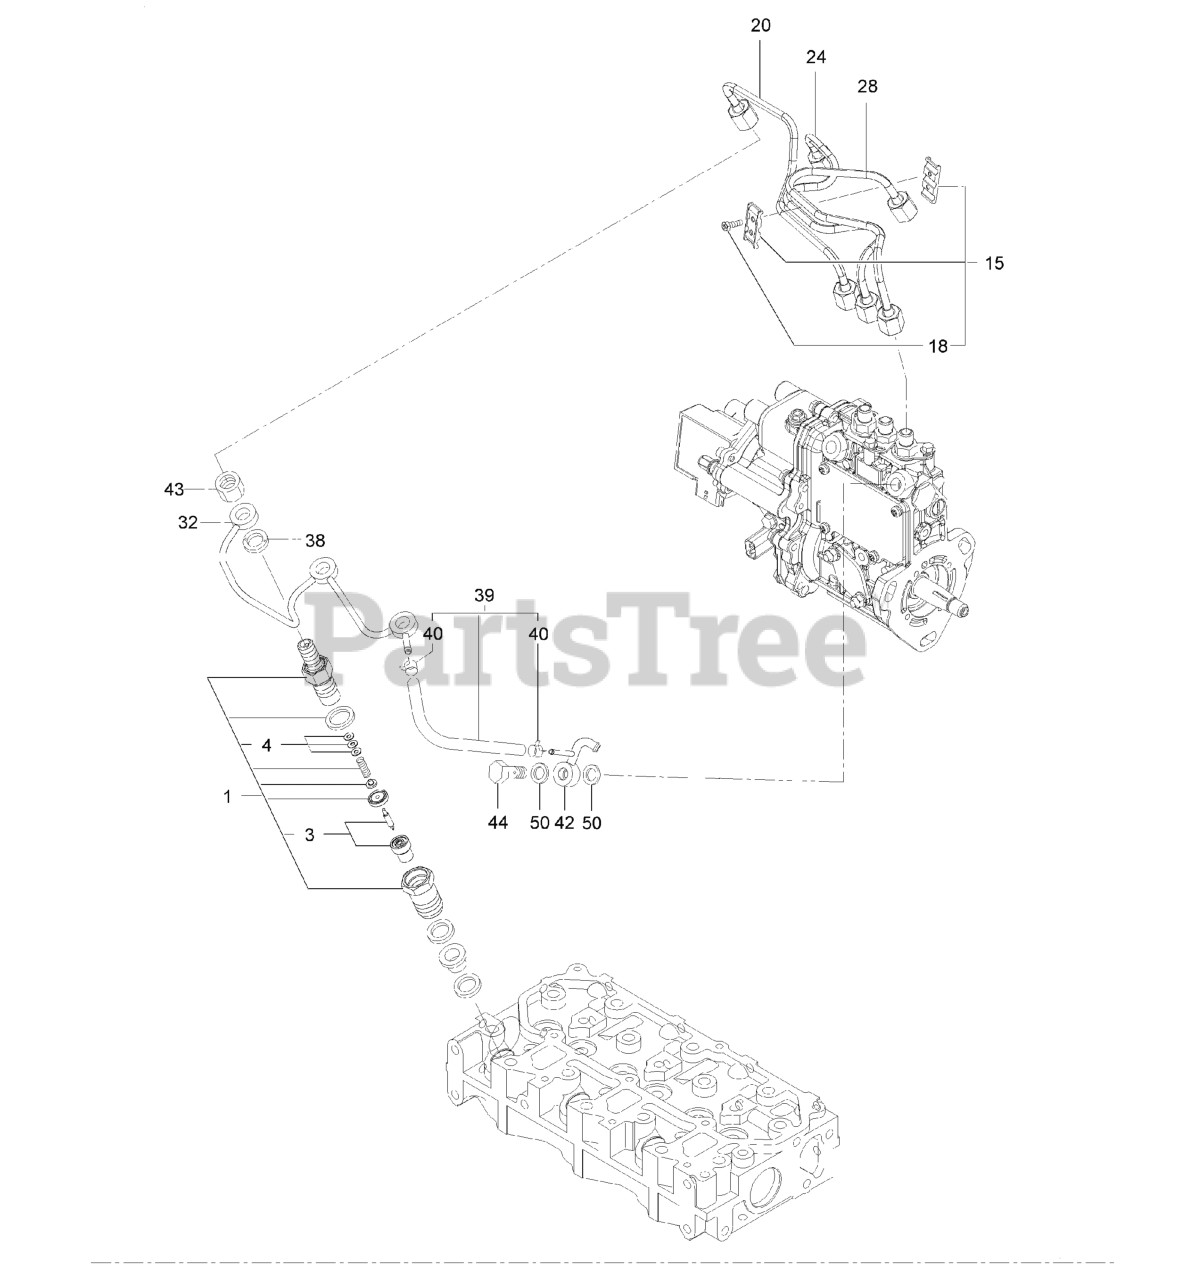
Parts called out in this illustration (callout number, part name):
1	NOZZLE ASM
3	NOZZLE ASM
4	SHIM SET-ADJUSTING
15	RETAINER-PIPE
20	PIPE ASM
24	PIPE ASM
28	PIPE ASM
32	PIPE ASM
39	HOSE ASM
40	CLAMP-HOSE
42	JOINT-OVER FLOW
43	NUT-NOZZLE
44	VALVE ASM-CHECK
50	WASHER-SEAL
